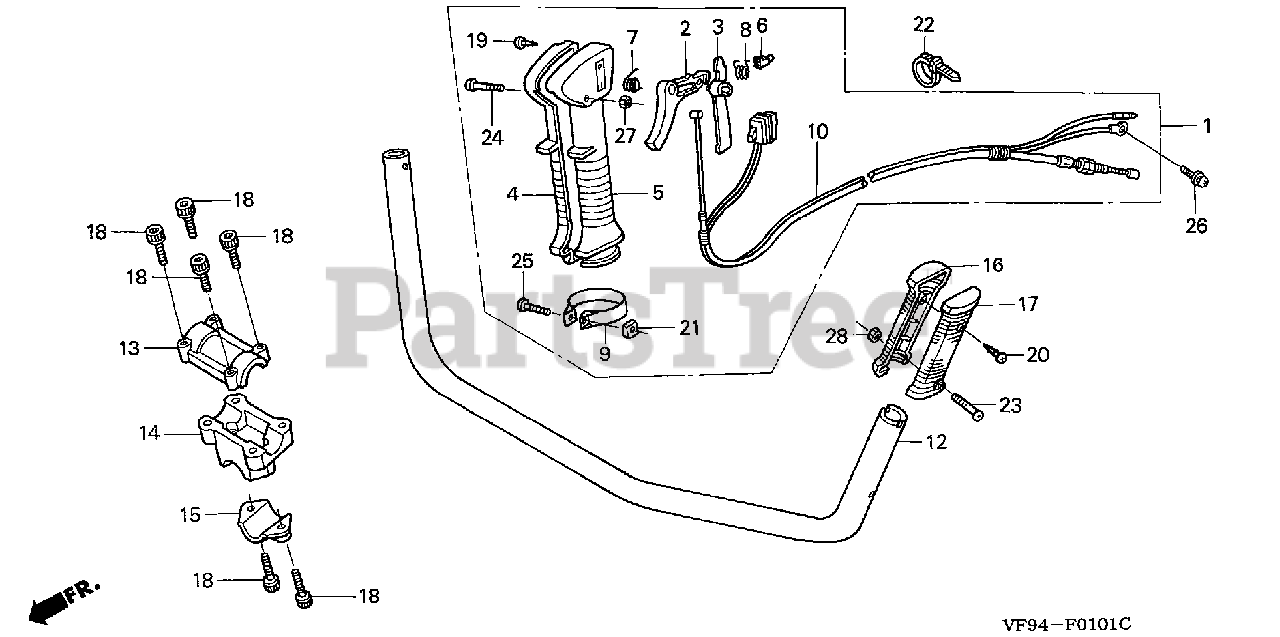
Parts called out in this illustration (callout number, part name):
1	LEVER ASSY., THROTTLE
2	LEVER, THROTTLE
3	LEVER, THROTTLE LOCK
4	GRIP, R. THROTTLE LEVER
5	GRIP, L. THROTTLE LEVER
6	BUTTON, THROTTLE LOCK
7	SPRING, THROTTLE LEVER
8	SPRING, THROTTLE LOCK LEVER
9	BRACKET, THROTTLE LEVER
10	WIRE HARNESS ASSY.
12	PIPE, HANDLE
13	HOLDER A, HANDLE
14	HOLDER B, HANDLE
15	HOLDER C, HANDLE
16	GRIP A, HANDLE
17	GRIP B, HANDLE
18	BOLT, SOCKET (6X30)
19	SCREW, TAPPING (4X18)
20	SCREW, TAPPING (5X16)
21	NUT, SQUARE (6MM)
22	BAND, WIRE HARNESS
23	SCREW, PAN (5X30)
24	SCREW, PAN (5X35)
25	SCREW, PAN (6X20)
26	SCREW-WASHER (5X12)
27	NUT, HEX. (5MM)
28	NUT, HEX. (5MM)
